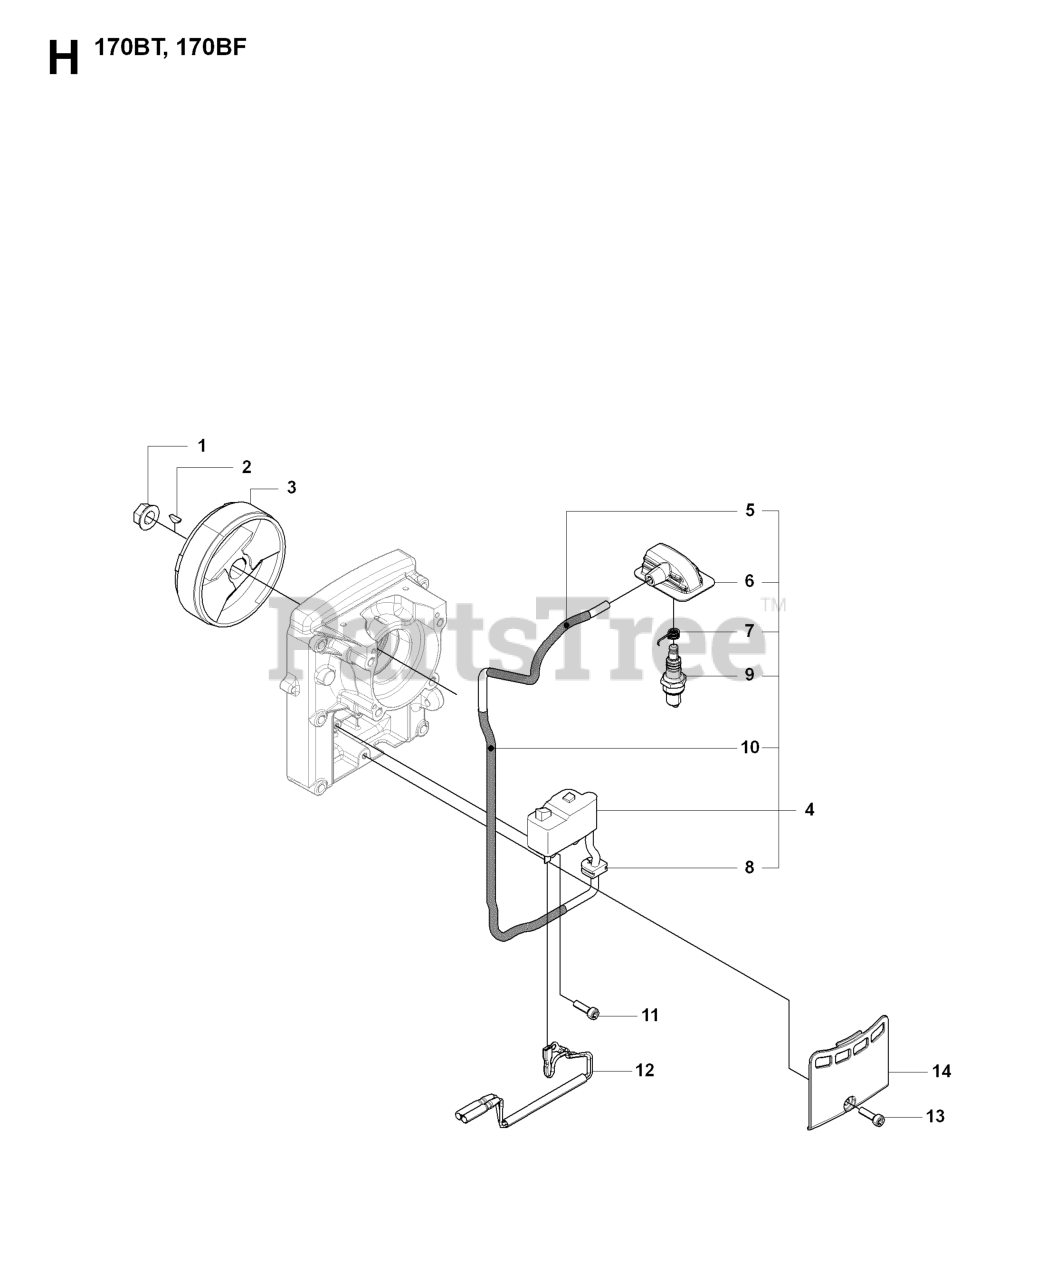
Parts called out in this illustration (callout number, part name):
8	GROMMET
9	SPARK PLUG NGK CMR7H
14	COVER
